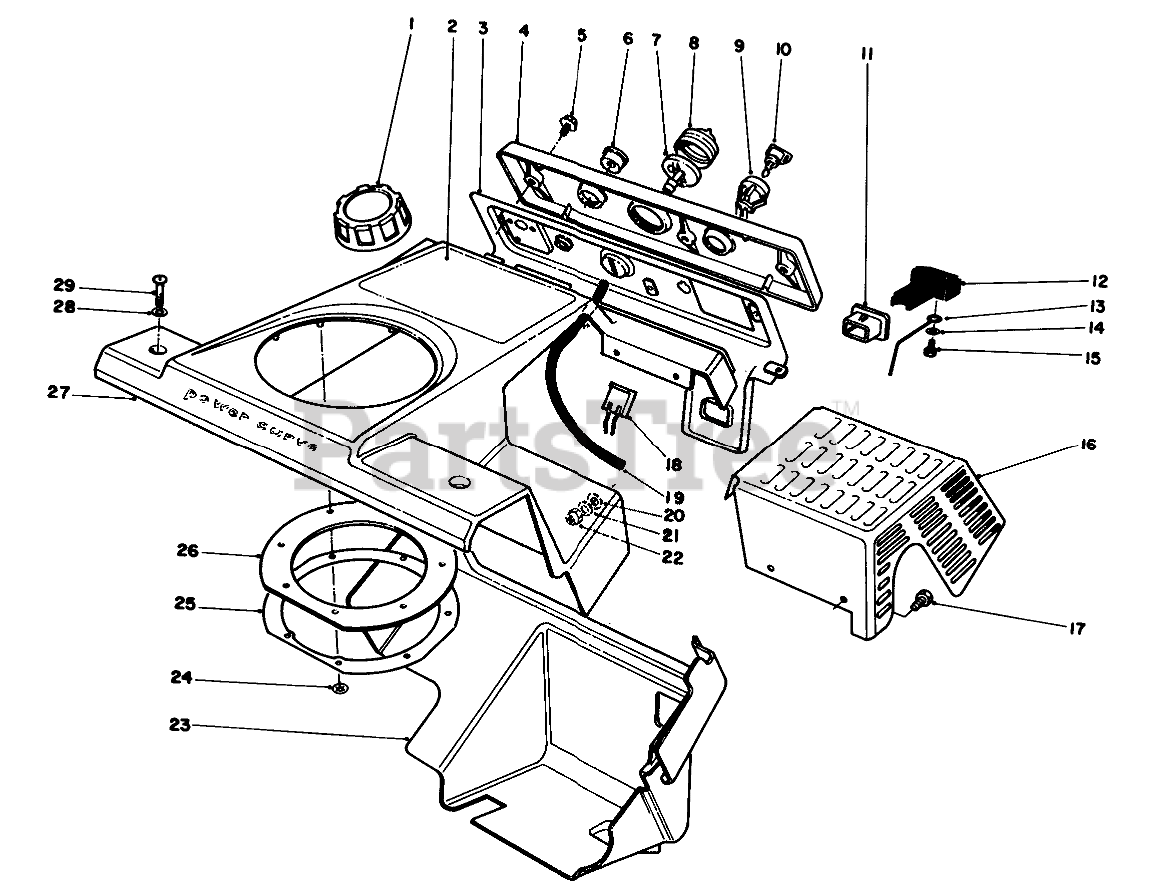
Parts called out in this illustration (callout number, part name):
1	CAP-FUEL ASM
2	DECAL - CCR 2000E
3	Control Panel Assembly (Incl. Ref. #6-8 & 11)
4	CONTROL NAMEPLATE
5	SCREW
6	GUIDE-ROPE, STARTER
7	BODY-PRIMER
8	BULB-PRIMER
9	SWITCH
10	KEY-IGNITION
11	FITTING
12	CONTROL-CHOKE
13	Linkage-Choke
14	WASHER-PLAIN
15	#8 X .625" PHILPS PAN H
16	Wa-Shield
17	SCREW-SHH
18	CONNECTOR-BODY
19	PRIMER HOSE
20	WASHER
21	WASHER-FLAT
22	NUT-LOCK, SIDE
23	Shroud-Lower
24	PALNUT
25	Retainer-Chute Seal
26	SEAL-CHUTE
27	Upper Shroud Assembly (Incl. Ref. #2 & 24-26)
28	WASHER-FLAT
29	SCREW-PPH
